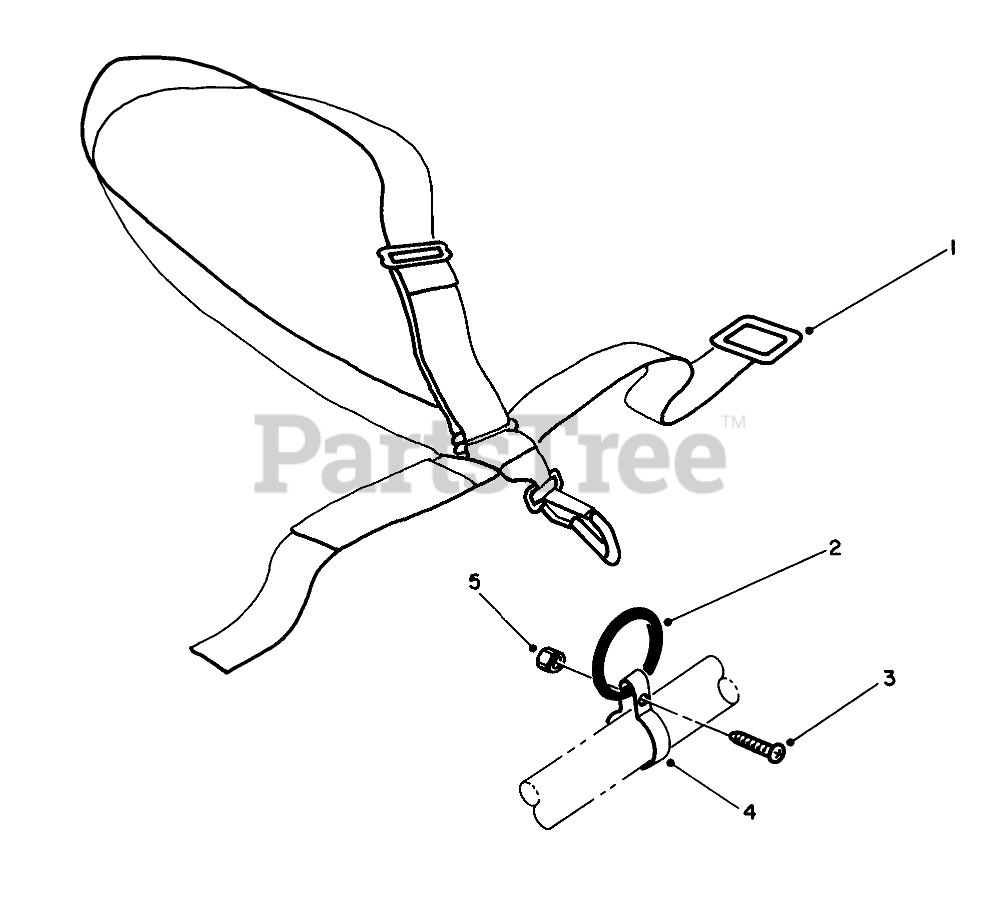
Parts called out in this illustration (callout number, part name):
1	Deluxe Harness
2	Ring
3	SCREW-SRH
4	Clamp
5	NUT-LOCK, NI
